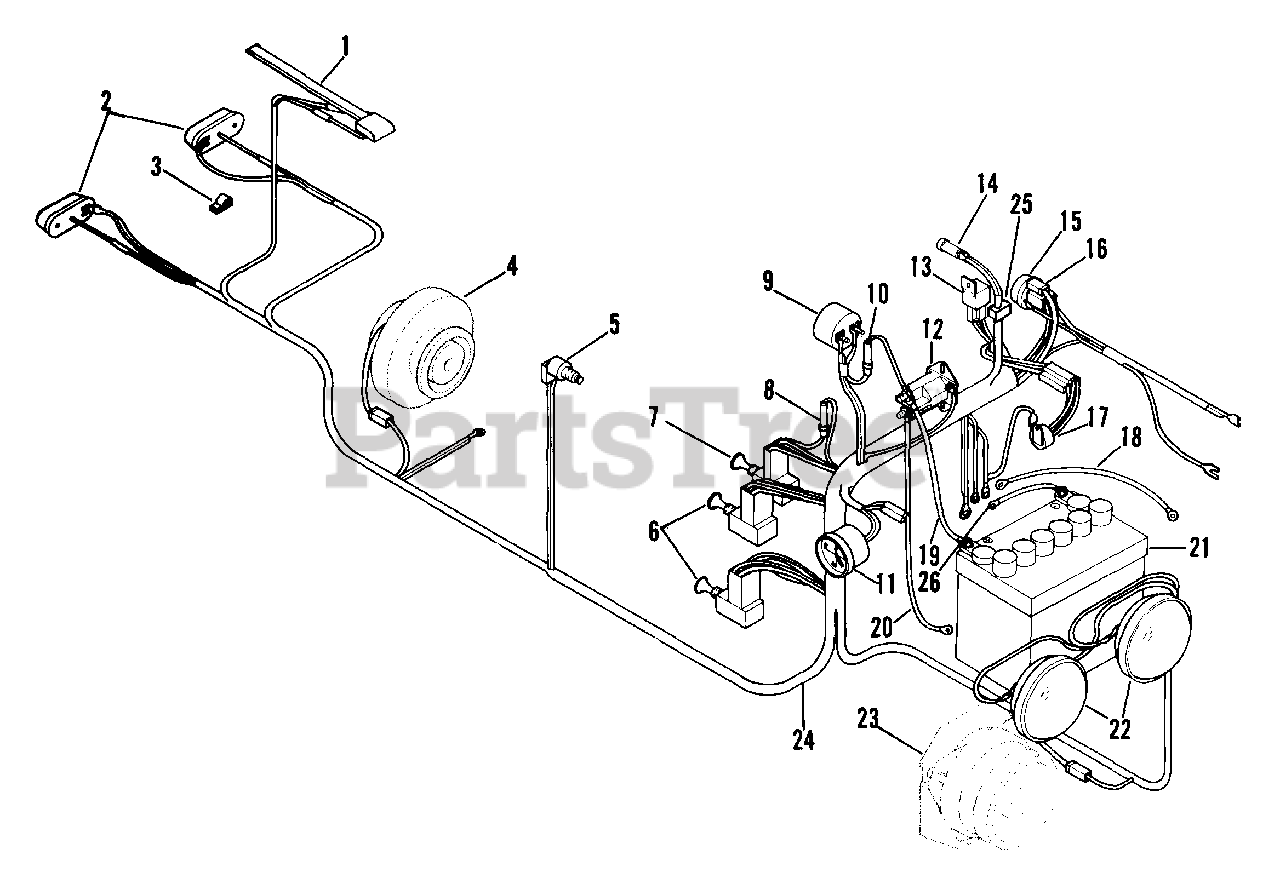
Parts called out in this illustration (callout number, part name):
1	SWITCH SEAT
2	TAIL LIGHT ASSEMBLY W/BULLET
2	TAIL LIGHT LENS
2	MALE DISCONNECT ADAPTER
2	SCR-MCH 10-24X.50 SLTR PL
2	WSHR-LK 10X.047 MED PL
2	NUT-HEX 10-24 PL
3	WIRE CLIP
4	ELECTRIC CLUTCH
5	SAFETY SWITCH
5	CONNECTOR
5	NUT-HEX .625-32 PL
6	CLUTCH SWITCH
6	CONNECTOR
6	WSHR-FL-STL .382X.812X.023 PL
7	LIGHT SWITCH
7	CONNECTOR
7	WSHR-FL-STL .382X.812X.023 PL
8	7 Amp Fuse
9	AMMETER
9	WSHR-LK-EXT #10 ID X .022
9	NUT 10-32 PL
10	30 Amp Fuse
11	HOUR METER
12	SOLENOID
12	WSHR-LK-EXT #10 ID X .022
12	NUT 10-32 PL
12	WSHR-LK-INT .313X.030 PL
12	NUT-JAM .312-24 PL
12	BLT-HEX .25-20X.75 PL GR2
12	BLT-HEX .25-20X1.00 GR2
12	WSHR-FL-STL.281X.62X.065 PL
12	WSHR-LK-EXT. 250 ID
13	RELAY
14	PTO INDICATOR LIGHT
14	LAMP SOCKET
14	SPEED NUT
15	SWITCH ASSEMBLY
15	CONNECTOR HOUSING
15	WSHR-LK-INT .563X.040 PL
15	NUT .562-24
16	DIODE ASSEMBLY
16	SCR-TAP .250-20X.50 HXSLHDPL
17	TIME DELAY MODULE
17	SCR-MCH 10-24X.50 SLTR PL
17	WSHR-LK 10X.047 MED PL
17	NUT-HEX 10-24 PL
18	GROUND CABLE .31X22.00X.31
19	GROUND CABLE .25X6.50X.31
19	BATTERY CABLE
19	WSHR-LK .250X.077 HVY PL
19	NUT-HEX .250-20 PL
20	STARTER CABLE .25X.35.25X.31
20	GROUND CABLE
21	BATTERY
22	HEAD LIGHT
22	HEAD LIGHT RETAINER RING
22	SCR-MCH 10-24X.50 SLTR PL
22	WSHR-FL-STL .250X.562X.049 PL
23	DIESEL CLUTCH ASSEMBLY
23	CLUTCH ASSEMBLY 1 1/8 BORE
23	CLUTCH ASSEMBLY 1-1/4 BORE
24	WIRING HARNESS
24	WIRING HARNESS - DIESEL
25	MOLDED DIODE PLUG 1 AMP
26	STARTER CABLE 6.75"
27	CONNECTOR
